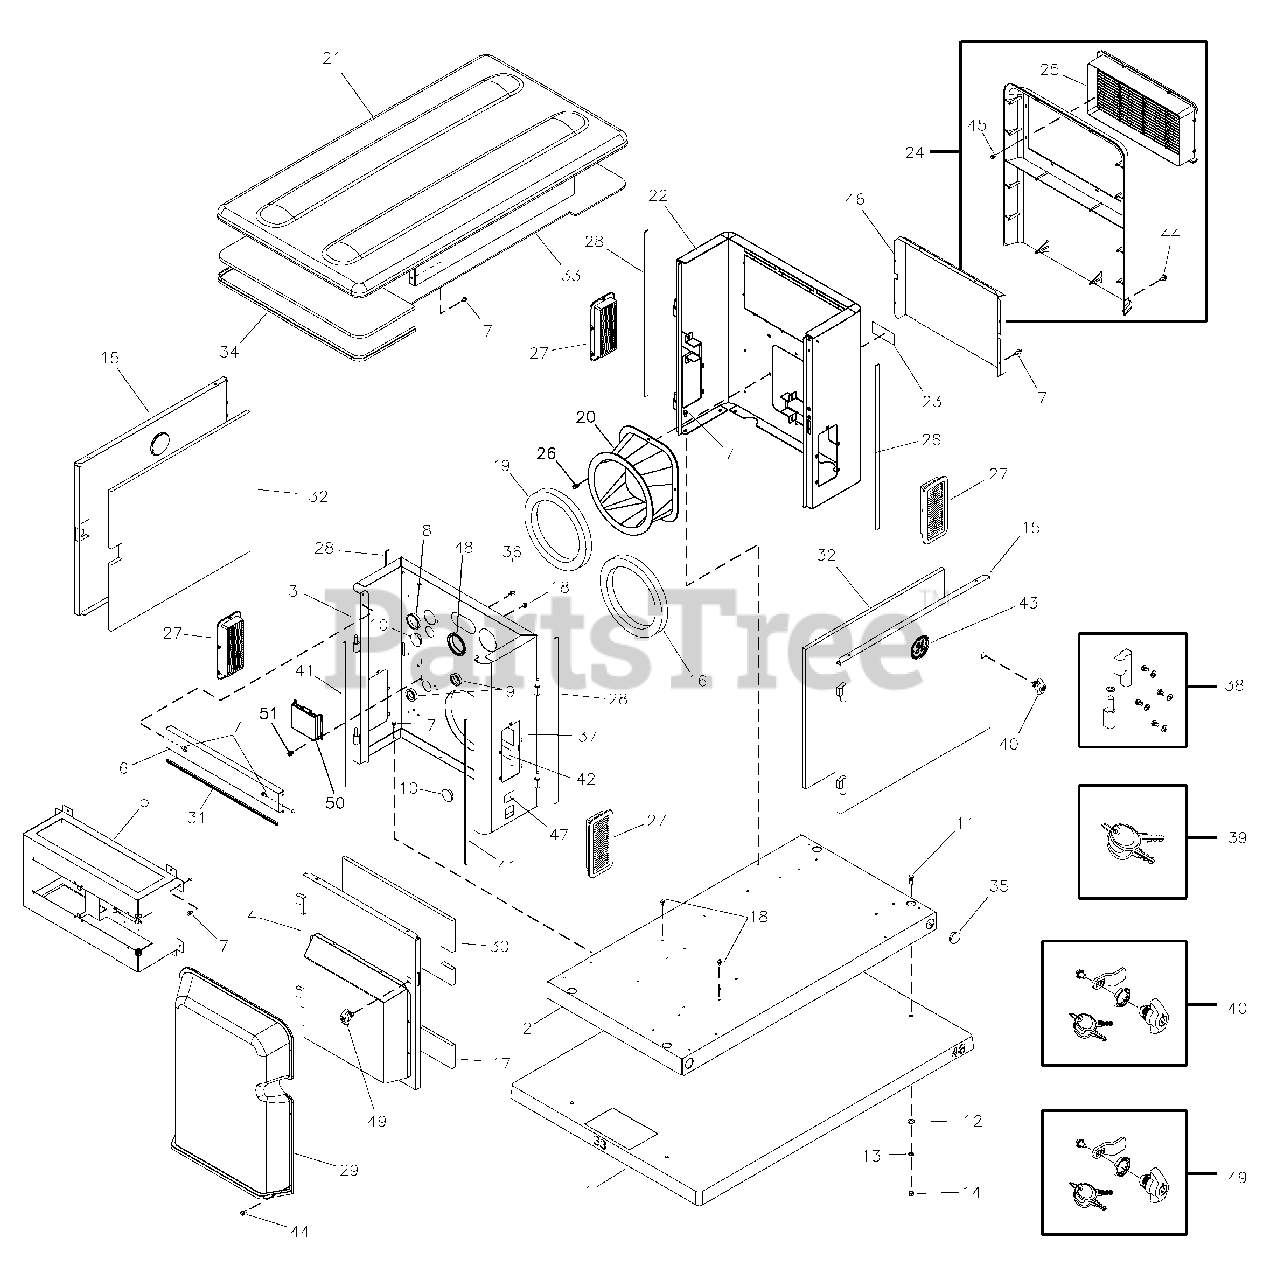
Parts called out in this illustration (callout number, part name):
3	BULKHEAD, Engine
4	DOOR
5	DUCT
6	SUPPORT, Rail
7	BOLT
11	* CAPSCREW, Hex Head, 3/8-16 x 1
12	* WASHER, Flat, 3/8-M10
13	* WASHER, Lock, 3/8
14	* NUT, 3/8-16
15	DOOR
16	SEAL, Foam
18	MOUNT, Tie Wrap
19	SEAL, Foam
20	ADAPTER, Alternator
21	ROOF
22	BULKHEAD, Alternator
42	DECAL
47	DECAL
50	REGULATOR, Voltage
